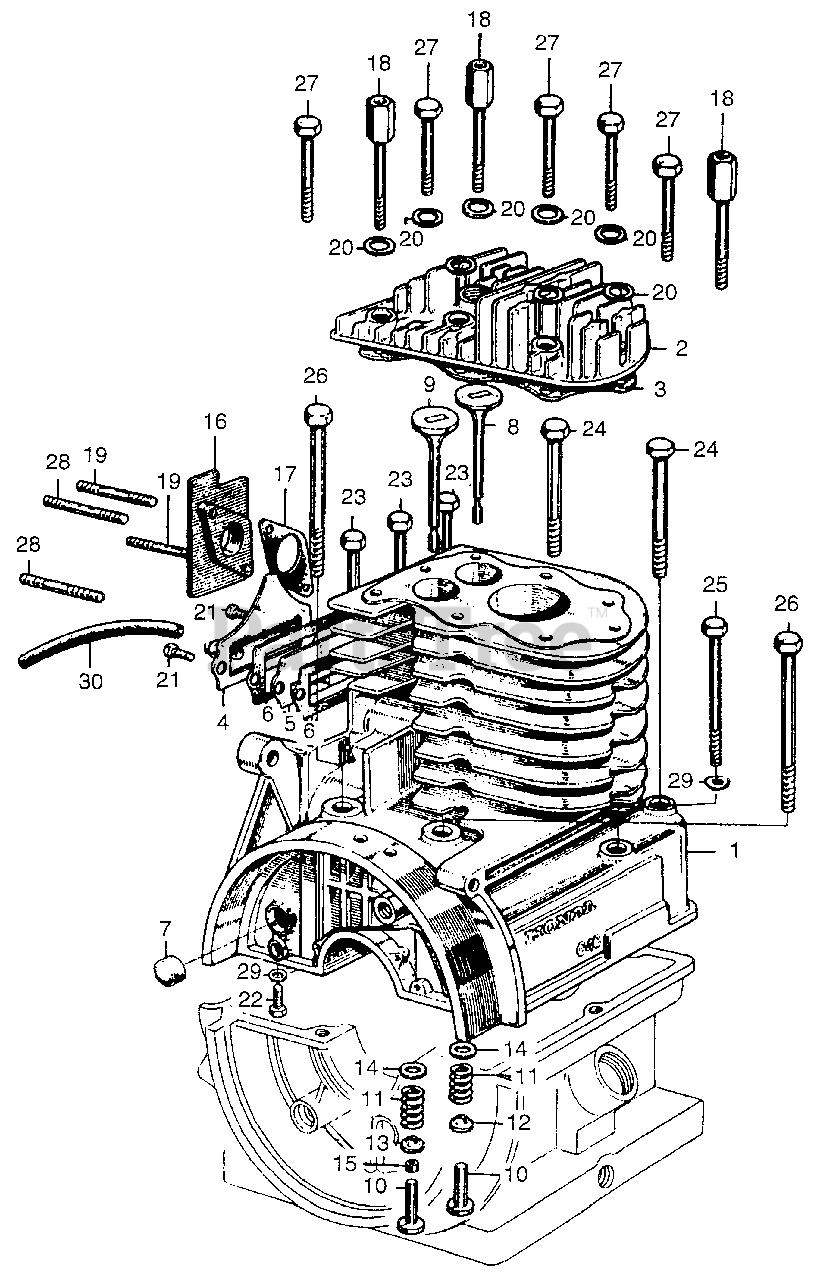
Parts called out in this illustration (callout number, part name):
2	CYLINDER HEAD (NOT AVAILABLE)
3	GASKET, CYLINDER HEAD (NOT AVAILABLE)
4	COVER, TAPPET
5	SEPARATOR, OIL
6	GASKET, BREATHER CASE
7	PLUG, CAMSHAFT SEALING (NOT AVAILABLE)
8	VALVE, IN. (NOT AVAILABLE)
9	VALVE, EX. (NOT AVAILABLE)
10	LIFTER, VALVE
11	SPRING, VALVE (NOT AVAILABLE)
12	RETAINER, VALVE SPRING
13	RETAINER, VALVE SPRING (NOT AVAILABLE)
14	SEAT, SPRING (NOT AVAILABLE)
14	SEAT, VALVE SPRING
15	ADJUSTER, TAPPET CLEARANCE (5.2/5.3) (NOT AVAILABLE)
15	ADJUSTER, TAPPET CLEARANCE (5.5/5.6) (NOT AVAILABLE)
15	ADJUSTER, TAPPET CLEARANCE (5.9/6.0) (NOT AVAILABLE)
16	INSULATOR, CARBURETOR (NOT AVAILABLE)
17	GASKET, CARBURETOR INSULATOR (NOT AVAILABLE)
18	BOLT, CYLINDER HEAD CLAMP
19	BOLT, STUD (8X42) (NOT AVAILABLE)
20	WASHER, HEAD (8MM)
21	BOLT, HEX. (6X16)
22	BOLT, HEX. (6X32)
23	BOLT, HEX. (6X70)
24	BOLT, HEX. (6X70)
25	BOLT, HEX. (6X80)
26	BOLT, HEX. (8X100)
27	BOLT, HEX. (8X45)
28	BOLT, STUD (6X18)
29	WASHER, PLAIN (6MM)
30	TUBE (8X125) (NOT AVAILABLE)
